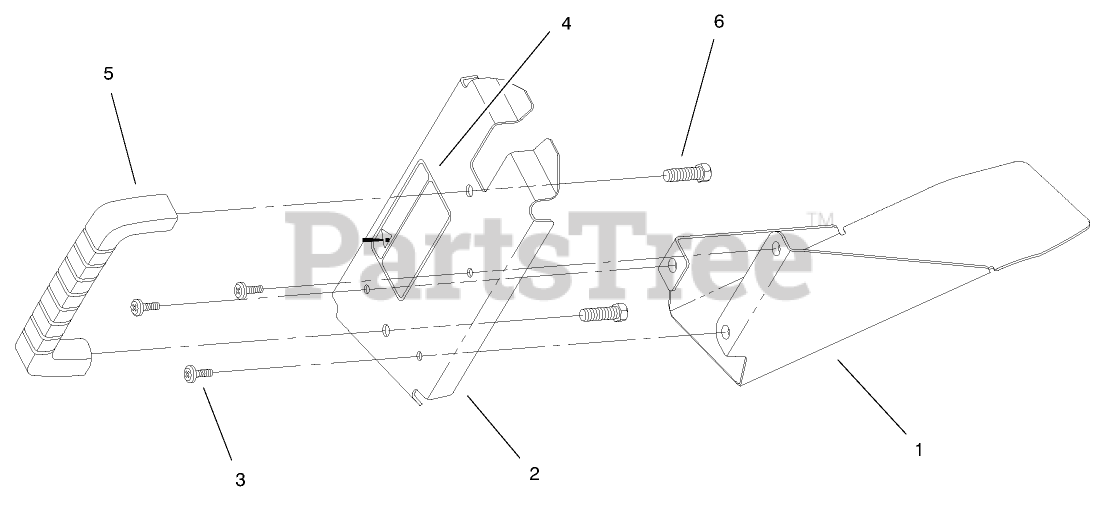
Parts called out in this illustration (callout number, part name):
4	DECAL - WARNING
5	HANDLE-DOOR
6	SCREW-HWH
